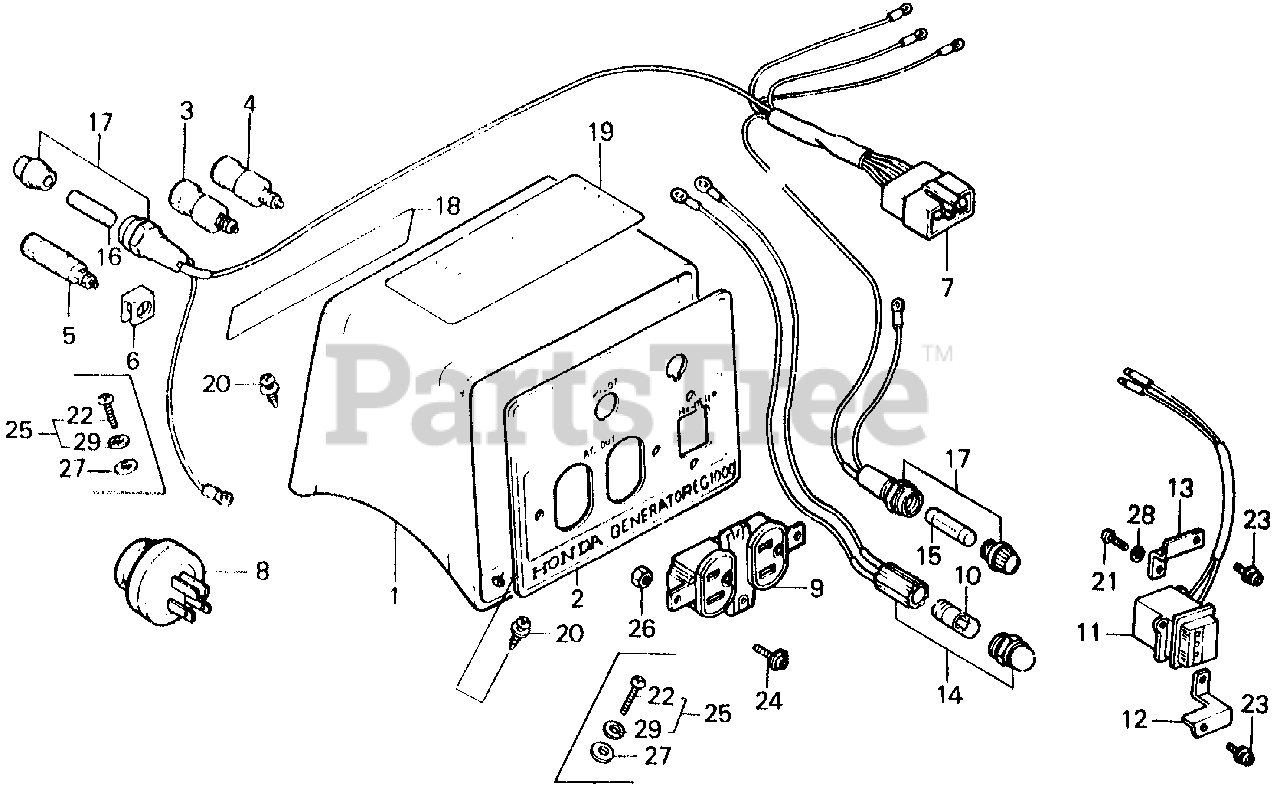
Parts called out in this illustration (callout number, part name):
1	BOX, CONTROL *R8* (BRIGHT RED)
2	PANEL, FR.
3	TERMINAL, D.C. OUT (+)
4	TERMINAL, D.C. OUT (-)
5	TERMINAL ASSY., GROUND
5	TERMINAL ASSY., GROUND (NOT AVAILABLE)
6	PLATE, GROUND
7	CONNECTOR, MALE (6 POLE)
8	PLUG ASSY., RECEPTACLE
9	RECEPTACLE (15A 125V)
9	RECEPTACLE (15A-125V)
10	BULB, DASH (24V3W)
10	BULB (24V2W)
11	METER, FREQUENCY
12	HOLDER A, FREQUENCY METER
13	HOLDER B, FREQUENCY METER
14	SOCKET ASSY., PILOT LAMP (NOT AVAILABLE)
15	FUSE (8A)
15	FUSE (10A)
16	FUSE (15A)
17	HOLDER ASSY., FUSE
18	MARK, D.C. OUTPUT
19	PLATE A, DESCRIPTION
20	SCREW, TAPPING (5X14)
21	SCREW, PAN (3X8)
22	SCREW, PAN (5X16)
23	SCREW-WASHER (4X10)
24	SCREW-WASHER (4X12)
25	SCREW-WASHER (5X16)
26	NUT, HEX. (4MM)
27	WASHER, PLAIN (5MM)
28	WASHER, SPRING (3MM)
29	WASHER, SPRING (5MM)
